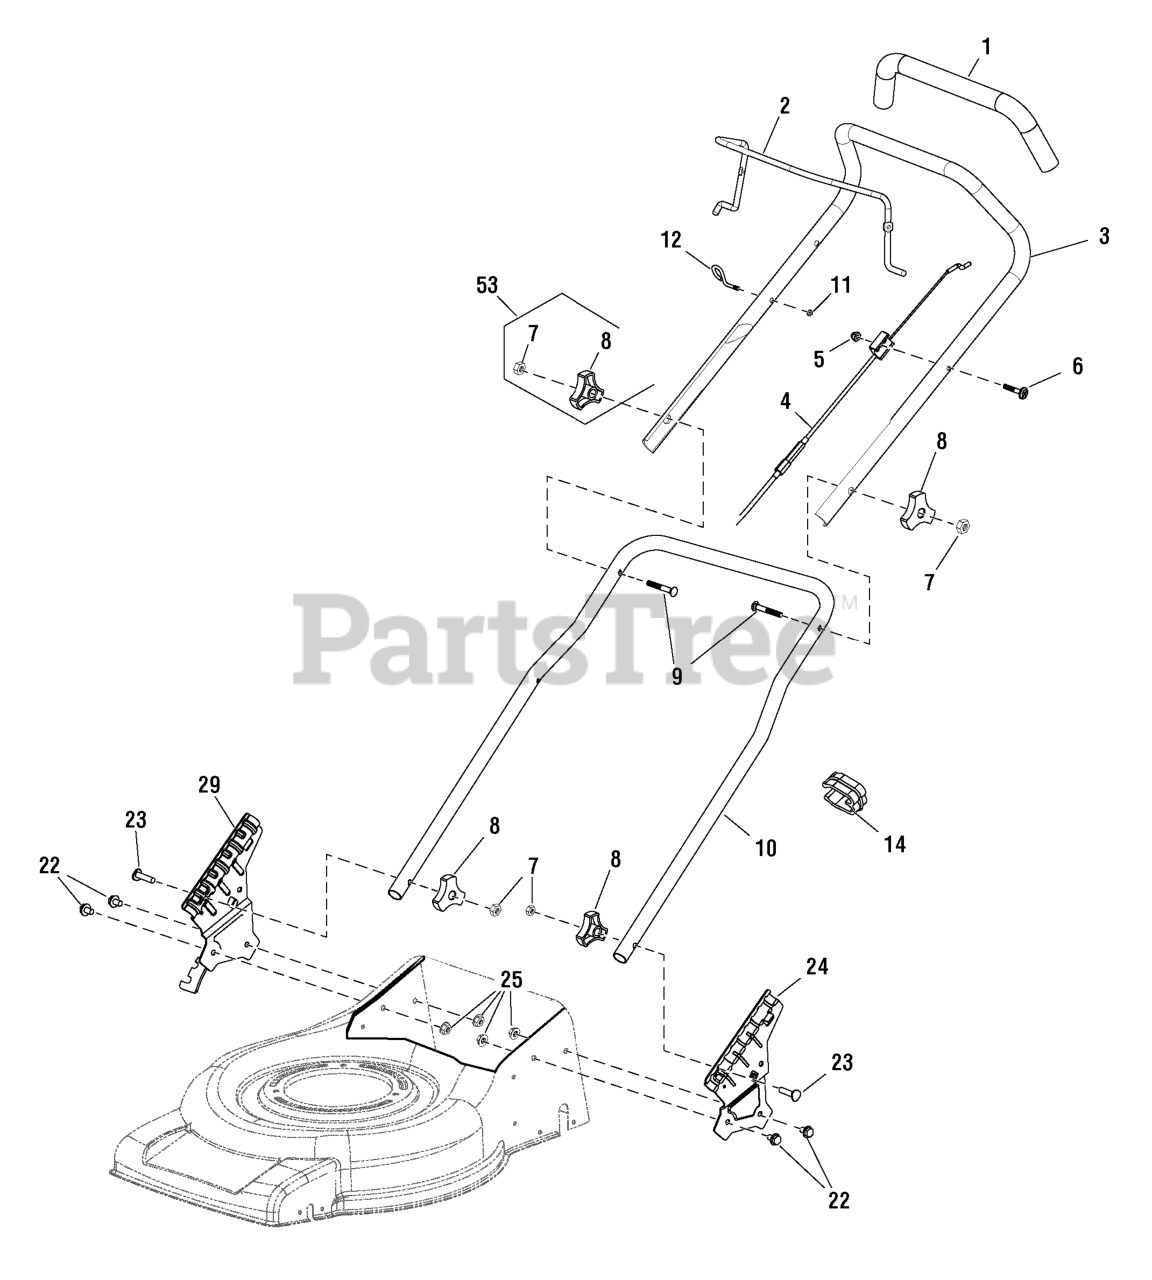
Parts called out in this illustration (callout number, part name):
3	HANDLE, Upper
4	CABLE, Brake
5	NUT, Acorn, M6
6	BOLT, M6 x 35
7	NUT, M8
9	BOLT, Step
10	HANDLE, Lower
11	NUT, M6
12	ROPE GUIDE
14	CLIP, Cable
22	BOLT, Hex Flange, M8 x 16
23	BOLT, Arc Head
24	BRACKET, Handle, Left
25	NUT, Hex, M8
29	BRACKET, Handle, Right
53	KIT, Hardware, Knob
